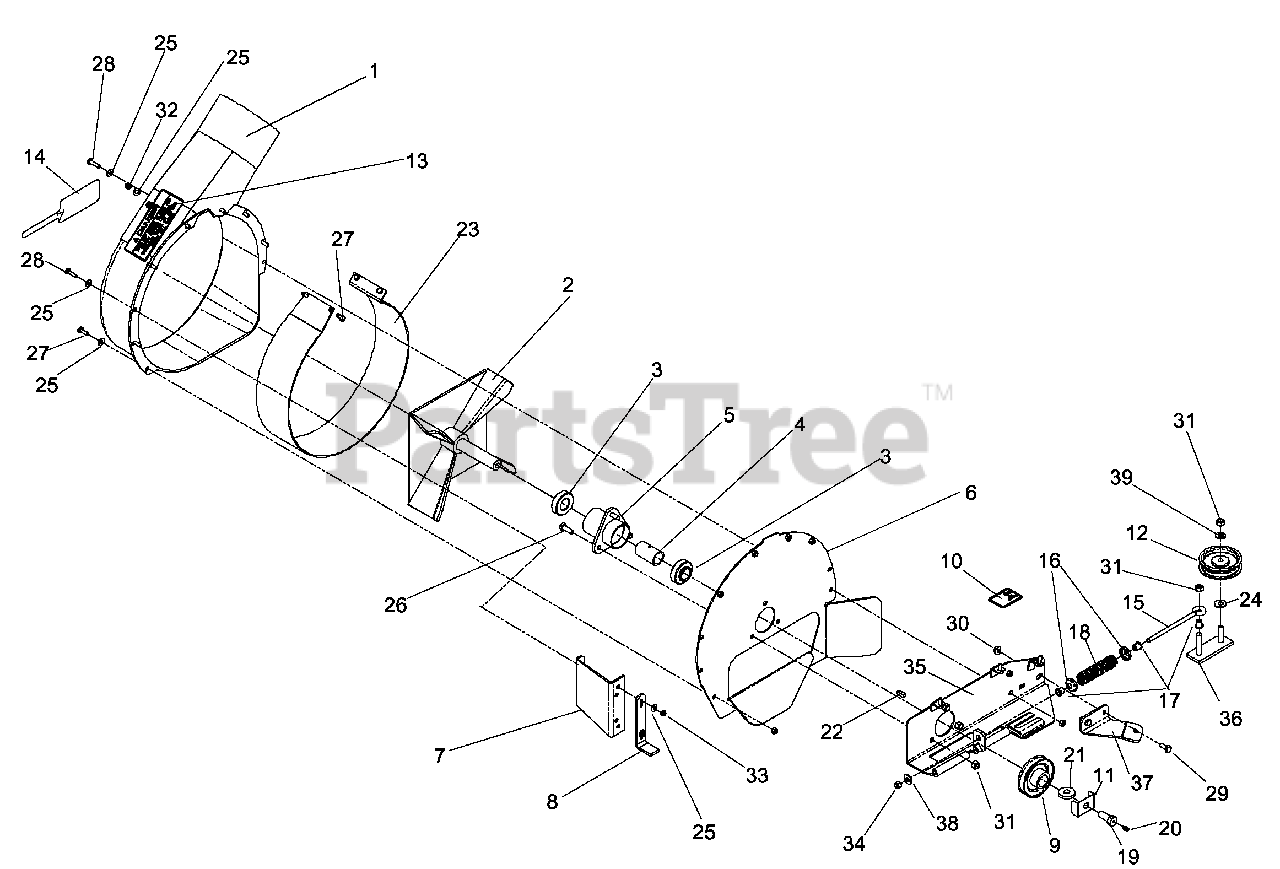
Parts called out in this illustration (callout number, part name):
2	FAN/SHAFT WLDT.
3	BEARING-ECC LOCK
4	SPACER 1 X 2.083
5	HUB WLDT-MACHINED
6	HOUSING PLATE
7	HOUSING GUARD
8	TIP GUARD
9	PULLEY - 3.5
10	DECAL, ROUTING 42"
12	PULLEY, IDLER 3 METAL
13	G.C.WARNING DECAL
14	DECAL, DIXON
15	EYE BOLT 5/16 X 6.00
16	SPRING RETAINER
17	FLIP-LOK BUSHING
19	HUB BOLT-DRILLED
20	ZERK, 3/16, DRIVE IN
21	WASHER .525 X 1.375 X .25
22	OUTER SHAFT KEY
23	SAND LINER
24	WASHER 3/8 FLAT
25	1/4` SAE FLAT WASHER
26	HCS 3/8C X 1
27	HCS 1/4C X 3/4 HCS
28	HCS 1/4C X 1
29	HCS 5/16C X 3/4
30	5/16-18 FLANGED L-NUT
31	NUT 3/8-16 NYLOC
32	NUT 1/4-20 NYLOC
33	JAM NUT 1/4C
34	NUT 5/16 NYLOC
35	IDLER BASE WLDT.
36	SLIDE ARM WLDT
37	IDLER MOUNT BRACKET
38	WASHER 5/16 FLAT
39	WASHER 3/8 SAE FLAT
